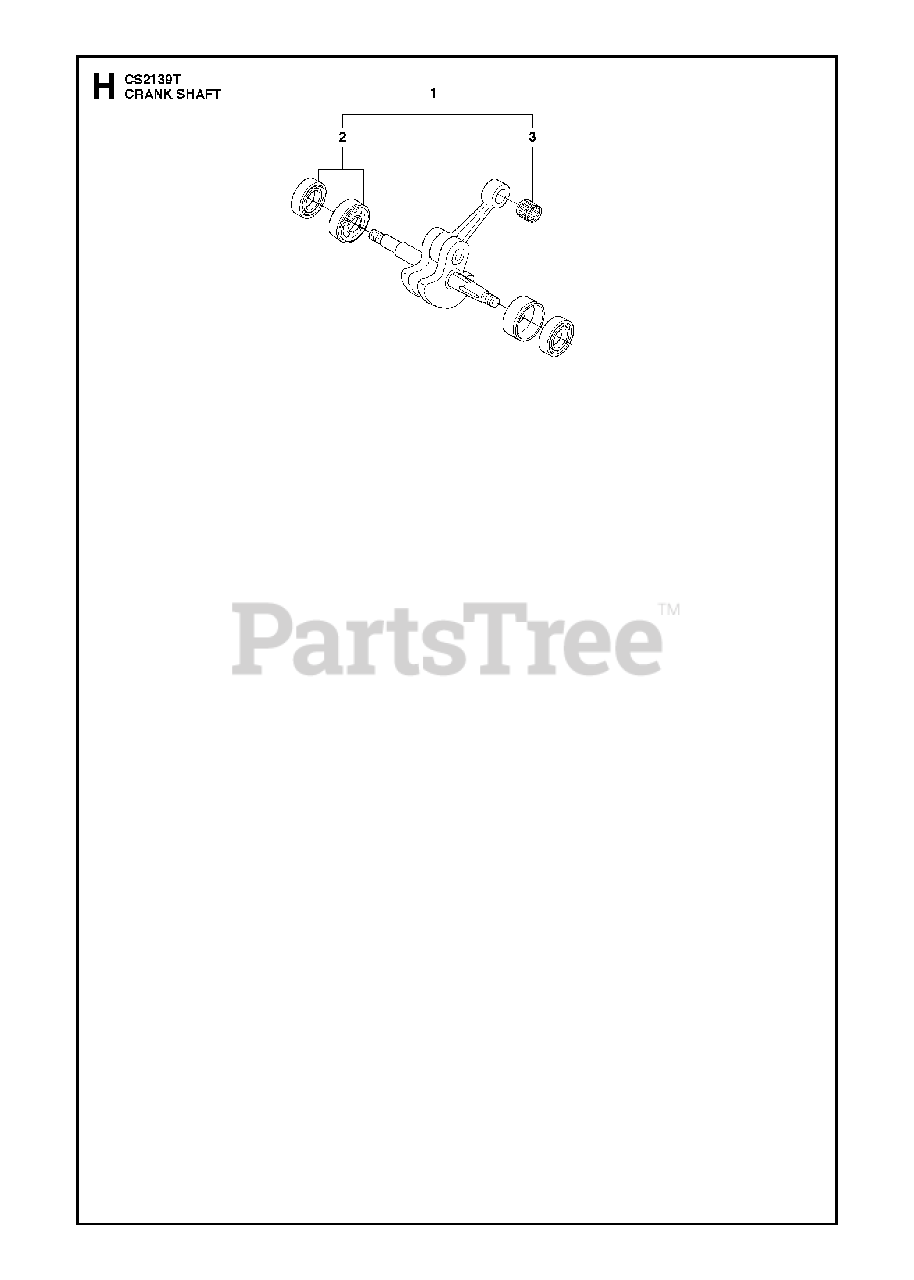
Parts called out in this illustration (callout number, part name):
1	CRANKSHAFT
2	HOLDER BALL BEARING
3	SUPPORT BUSHING
